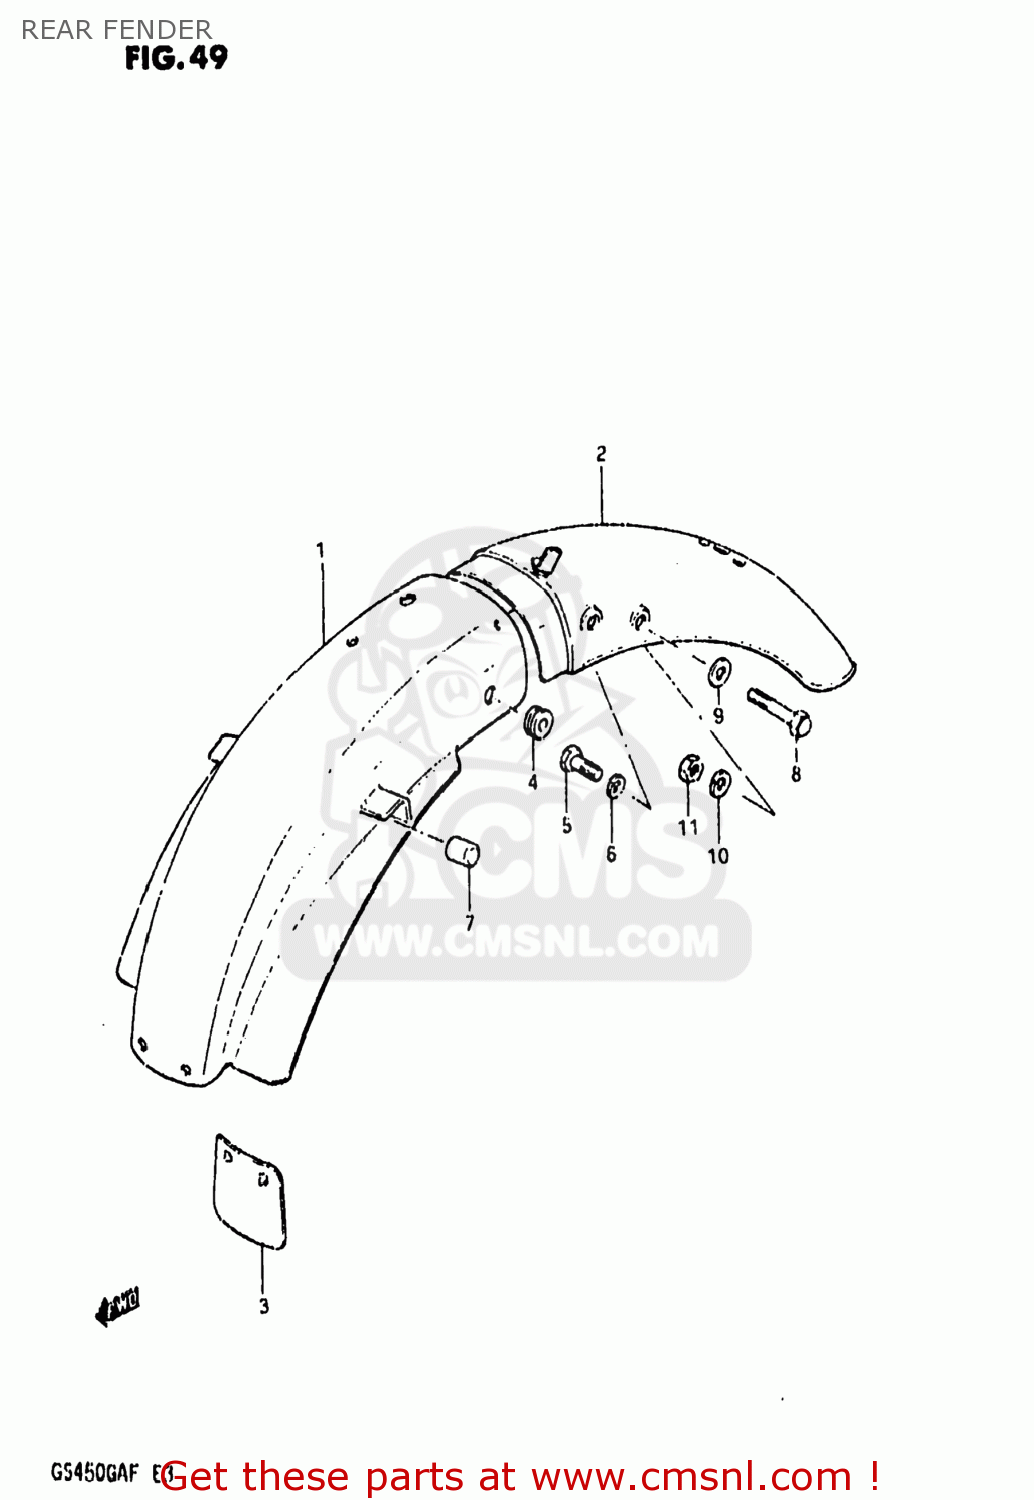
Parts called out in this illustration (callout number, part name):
1	BODY,REAR FENDER,FRONT
2	FENDER,REAR
3	GUIDE,RR FENDER MUD
4	CUSHION
5	BOLT 8X12
6	WASHER,LOCK,8.
7	CUSHION
8	BOLT
9	WASHER
10	LOCK WASHER
11	NUT
